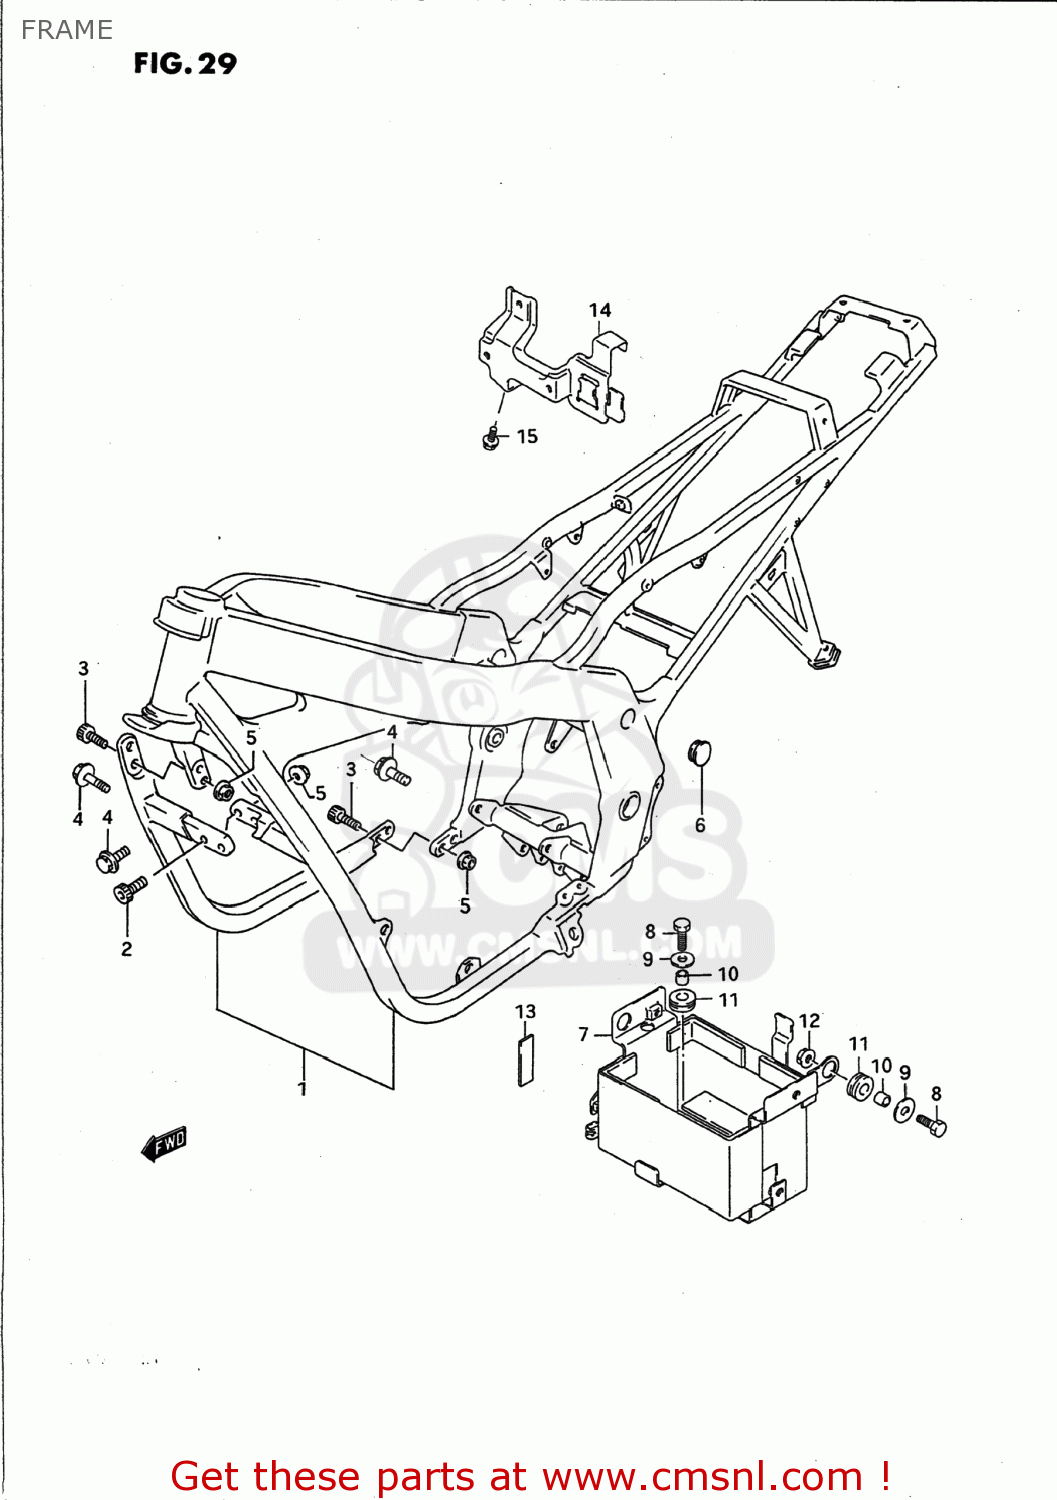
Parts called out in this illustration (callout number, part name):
1	FRAME
2	BOLT
3	BOLT
4	BOLT
5	NUT
6	CAP,BODY FRAME
7	HOLDER,BATTERY
8	BOLT
9	WASHER,COVER,FRONT
10	SPACER(6.2X9X7.5)
11	CUSHION
12	NUT
13	CUSHION
14	HOLDER,ELECTRIC PARTS
15	SCREW
